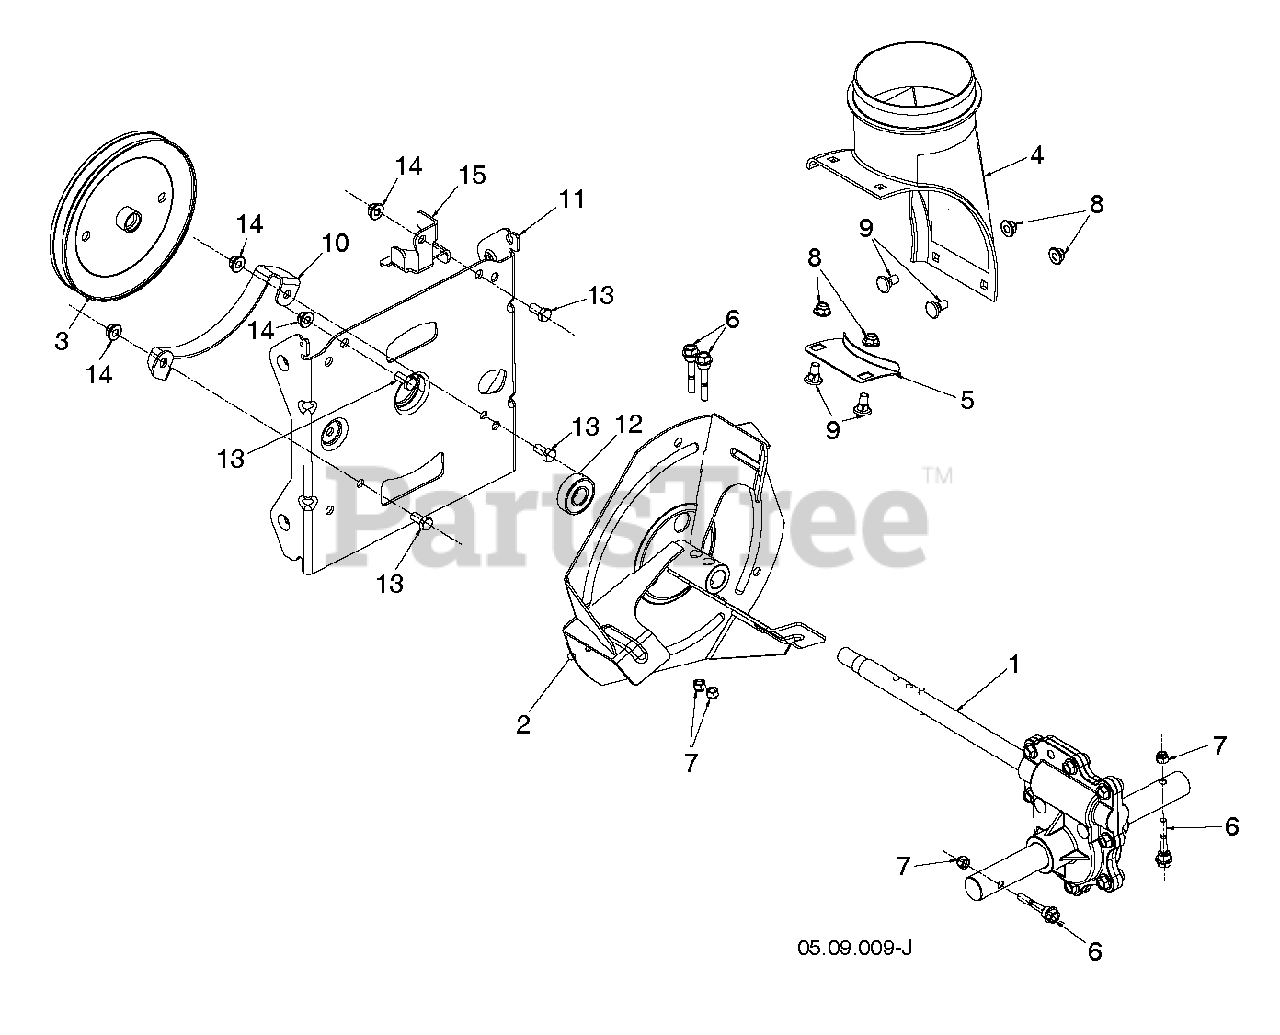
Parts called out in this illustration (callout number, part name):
1	GEARBOX.AUGER.
2	Impeller, Steel Snow Black
3	Screw-on Pulley, 7.3 5/8
4	Discharge Chute Base
5	BRACKET, CORNER DISCHARGE
6	Hex Head Shear Bolt, 1/4-20 X 1-13/16
7	LOCKNUT.NYLOC.1/4-20
8	Flange Hex Nut, Nylock Blk 5.16-1
9	Carriage Wafer Bolt, 5/16-18
10	BRACKET.BELT.KEEPER.LOWER.BLAC
11	Auger Housing Inter Bracket, Black
13	BOLT, HEX HEAD 5/16-18
14	NUTNYLOK.FLRANGE.5/16-18
15	Auger Belt Guide, Lower 479
